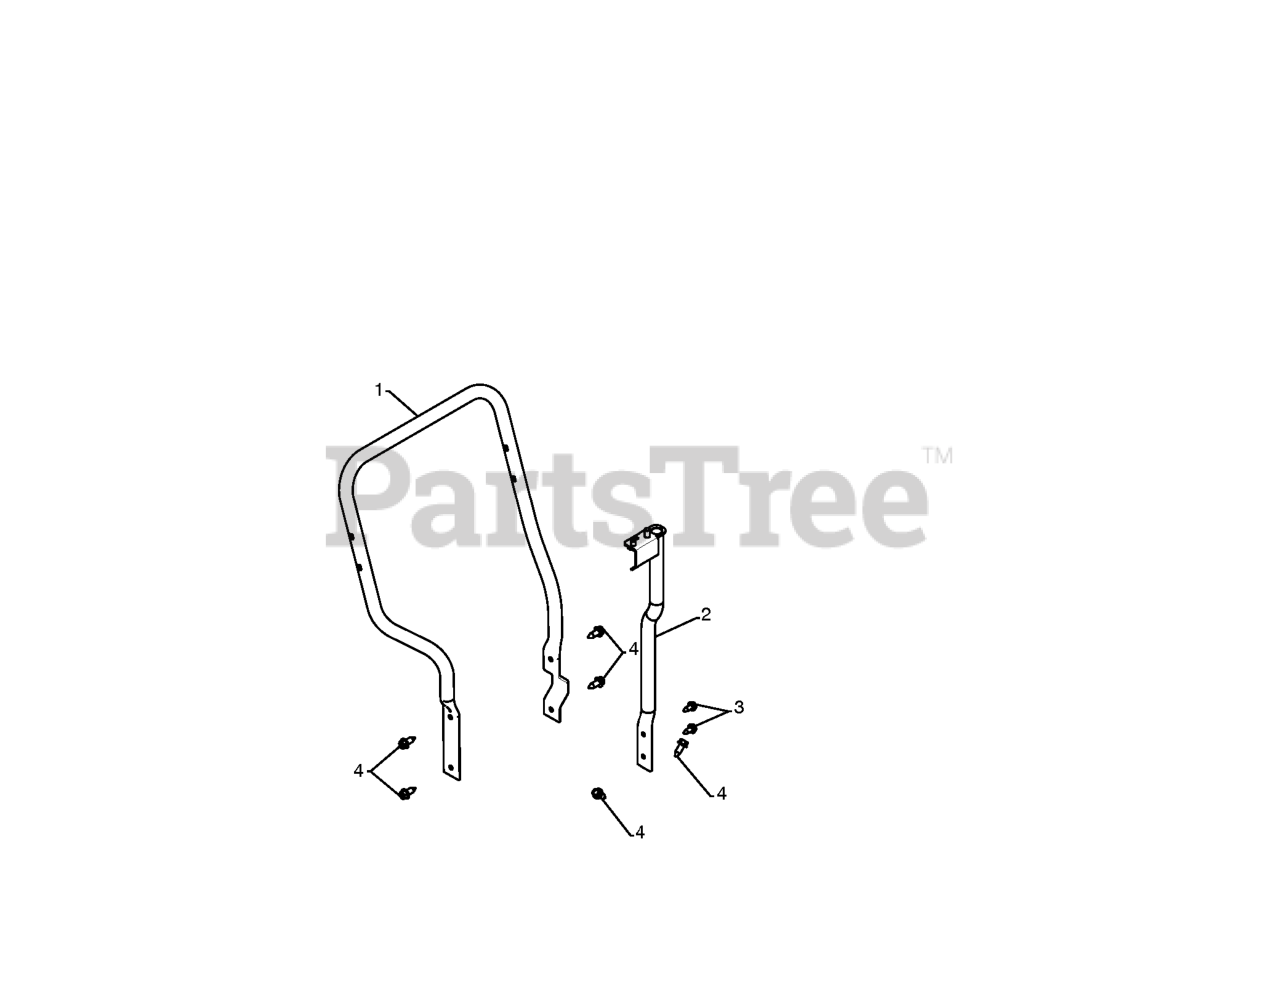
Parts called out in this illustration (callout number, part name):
1	TUBE.LOWER.HANDLE.SNOW.GRAY
2	SUPPORT.WELDMENT.ROTATOR.
3	BOLT.HEX.HD.WASHER.5/16-18X.75
4	SCREW 3/8-16X1
